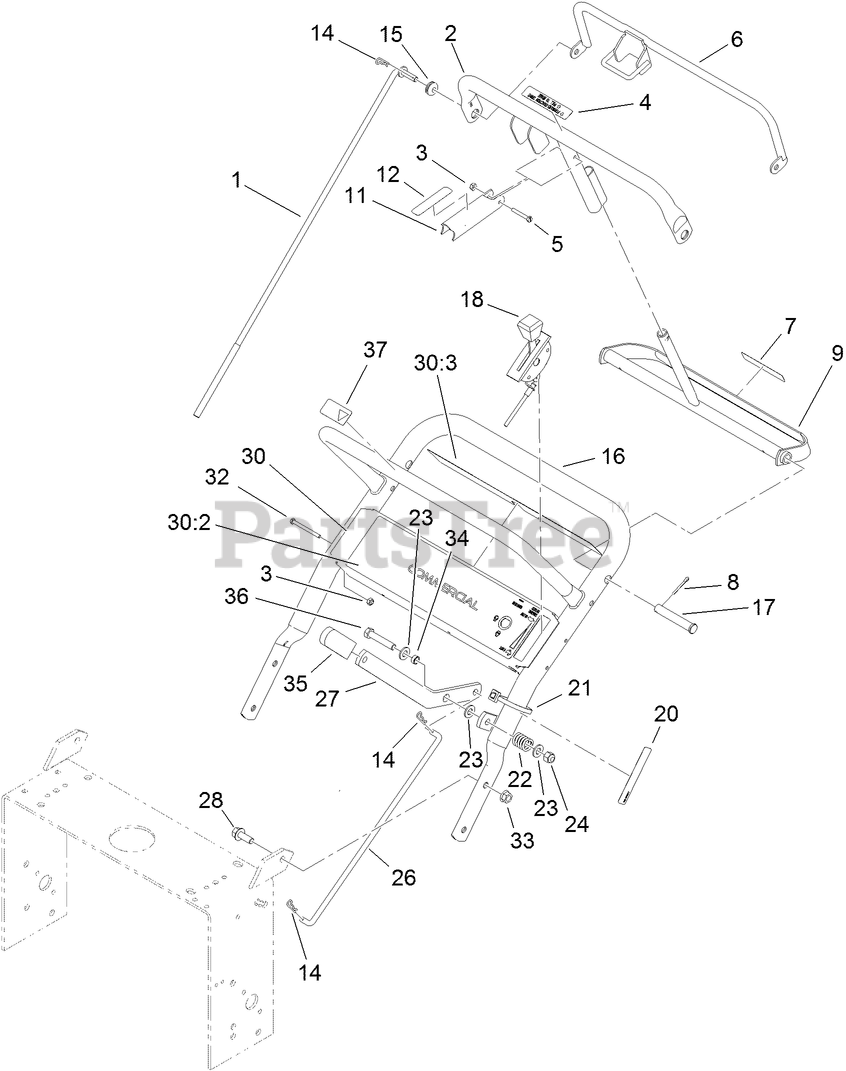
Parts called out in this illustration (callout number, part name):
1	ROD-CONTROL
2	BAR-CONTROL
3	NUT-LOCK, NI
4	DECAL
5	SCREW-SHH
7	DECAL
8	PIN-COTTER
9	CONTROL-PIVOT
11	LEVER-BRAKE, PARKING
12	DECAL
14	PIN-COTTER
15	GROMMET-RUBBER
16	HANDLE-UPPER
17	PIN-CLEVIS
18	CABLE-THROTTLE
20	DECAL-ENGAGE, DECK
21	TIE-PLASTIC
22	SPRING-COMPRESSION
23	WASHER-FLAT
24	NUT-LOCK, NI
26	LINKAGE-DRIVE, BLADE
27	LEVER-ENGAGEMENT, BLADE
28	SCREW-HHF
30	CONTROL PANEL ASM
30:2	DECAL-PANEL, CONTROL
30:3	DECAL-DANGER
32	SCREW-SHH
33	NUT-HF
34	SPACER
35	GRIP-LEVER
36	SCREW-HH
37	DECAL-PROTECTION, EAR
